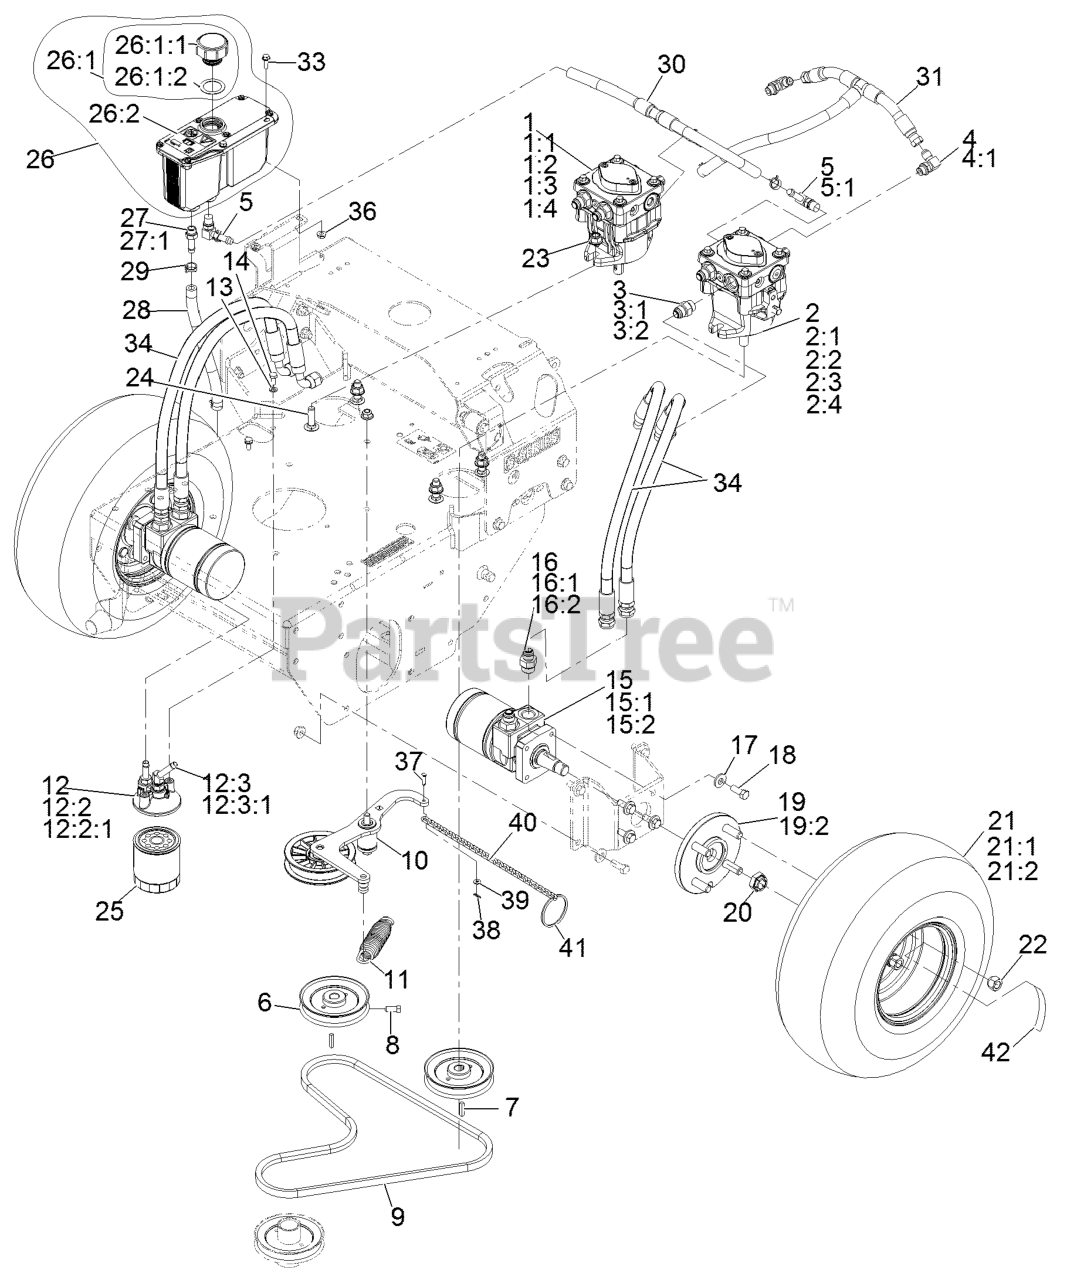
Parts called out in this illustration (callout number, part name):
1	RH HYD PUMP ASM
1:1	INPUT SHAFT KIT
1:2	BEARING-THRUST
1:3	CYLINDER BLOCK KIT
1:4	SEAL OVERHAUL KIT
2	LH HYD PUMP ASM
2:1	INPUT SHAFT KIT
2:2	BEARING-THRUST
2:3	CYLINDER BLOCK KIT
2:4	SEAL OVERHAUL KIT
3	FITTING-STRAIGHT
4	FITTING-ELBOW, 90 DEG
5	FITTING-ELBOW, 90
5:1	O-RING
6	SHEAVE ASM
8	SCREW-SET, SQH
9	BELT
10	ASM, PUMP IDLER
11	SPRING-EXTENSION
12	ASM, FILTER HEAD
12:2	ADAPTER-STRAIGHT
12:2:1	O-RING
12:3	FITTING-BARBED, 45 DEG
12:3:1	O-RING
13	WASHER-LOCK
14	SCREW-HH
15	HYD MOTOR ASM
15:1	SEAL KIT
15:2	BEARING AND SEAL KIT
16	FITTING-STRAIGHT
16:1	O-RING
17	WASHER-BELLEVILLE
18	SCREW-HH
19	WHEEL HUB ASM
19:2	STUD-WHEEL
20	NUT-LOCK
21	WHEEL AND TIRE ASM
21:1	TIRE-TURFMASTER
21:2	RIM-WHEEL
22	NUT-LUG
23	NUT-HF, NI
24	SCREW-HH
25	FILTER-25 MICRON, BI-DIRE
26:1	Reservoir-HYD
26:1:1	Cap-Reservoir, HYD
26:1:2	GASKET-CAP
26:2	DECAL-WARNING
27	ADAPTER-STRAIGHT
27:1	O-RING
28	HOSE-CHARGE
29	CLAMP-HOSE
30	HOSE-CASE DRAIN
31	HOSE-CHARGE
33	SCREW-HWH
34	HYD HOSE ASM
37	PIN-CLEVIS
38	PIN-HAIR
39	WASHER-PLAIN
40	CHAIN-LINK, TWIST
41	RING-SPLIT
42	DECAL-TORQUE WHEEL LUG-HU
